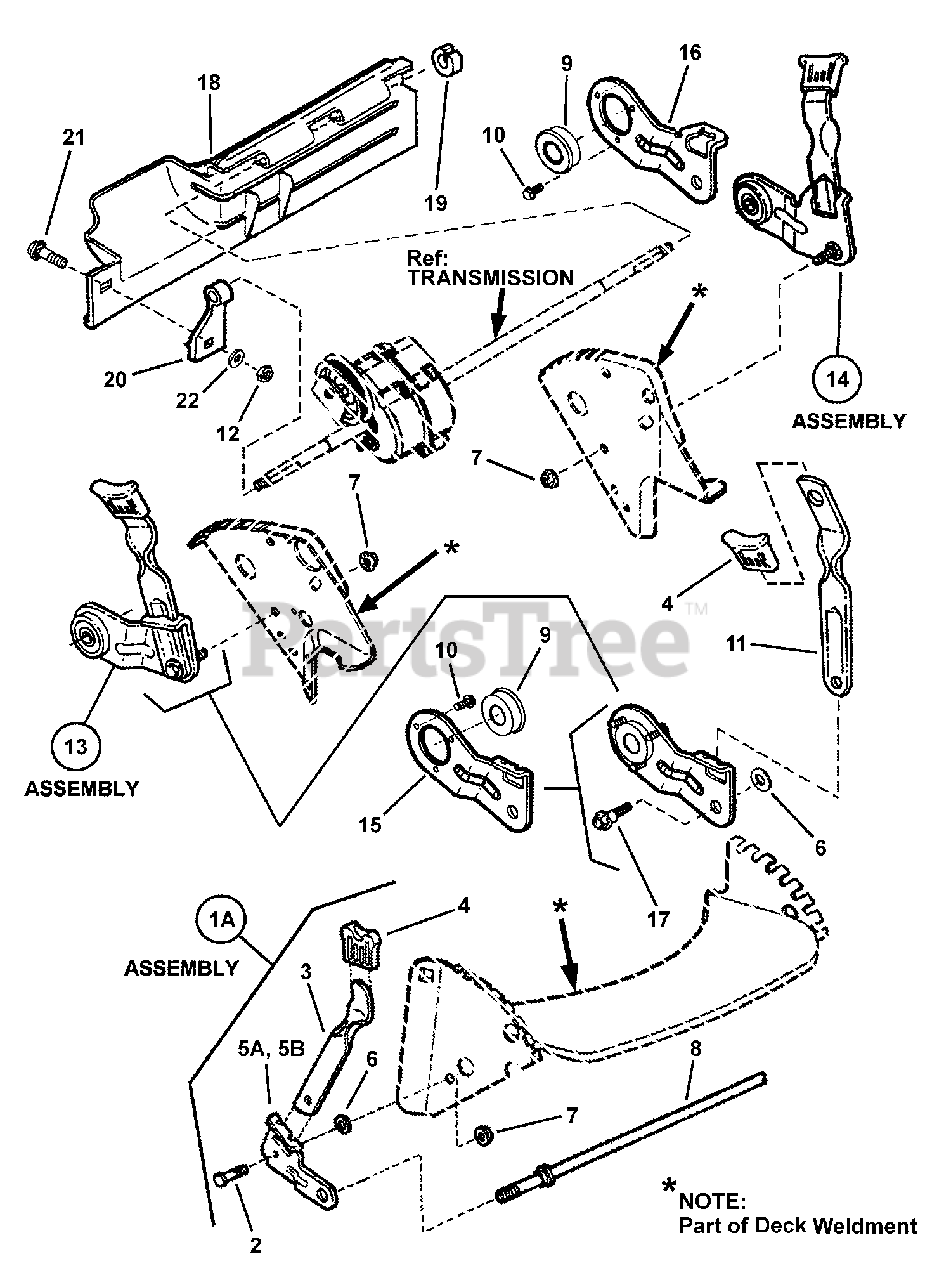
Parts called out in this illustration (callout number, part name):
1A	ASSEMBLY, Right Wheel Arm
2	BOLT, 5/16-18 x 3/4" Hex Washer Face Shoulder
3	LATCH, Height
4	GRIP, Height Latch
5A	WHEEL ARM, R.H. Front (Round Hole)
6	RETAINER, 5/16" Bolt
7	NUT, 5/16-18 Hex Flange Lock, GR 5
8	AXLE, 21"
9	BEARING, 9/16" I.D.
10	SCREW, #10-32 x 3/8" Hex washer Self-Tap
11	LATCH, Height Adjusting (long)
12	NUT, 1/4-20 Hex, GR 5 or B
13	ASSY, Wheel Arm, Right Rear (S.P.)
14	ASSY, Wheel Arm Left Rear Long (S.P.)
15	ARM, Wheel, Right Rear
16	ARM, Wheel, Left Rear
17	BOLT, 5/16-18 x 1" Hex Washer Face Shoulder
18	FOOT GUARD, Rear
19	RING, Split (Black)
20	SUPPORT, Foot Guard
21	BOLT, 1/4-20 x 1/2" Short Neck Carriage GR 5
22	WASHER, 1/4" Internal Tooth Lock
